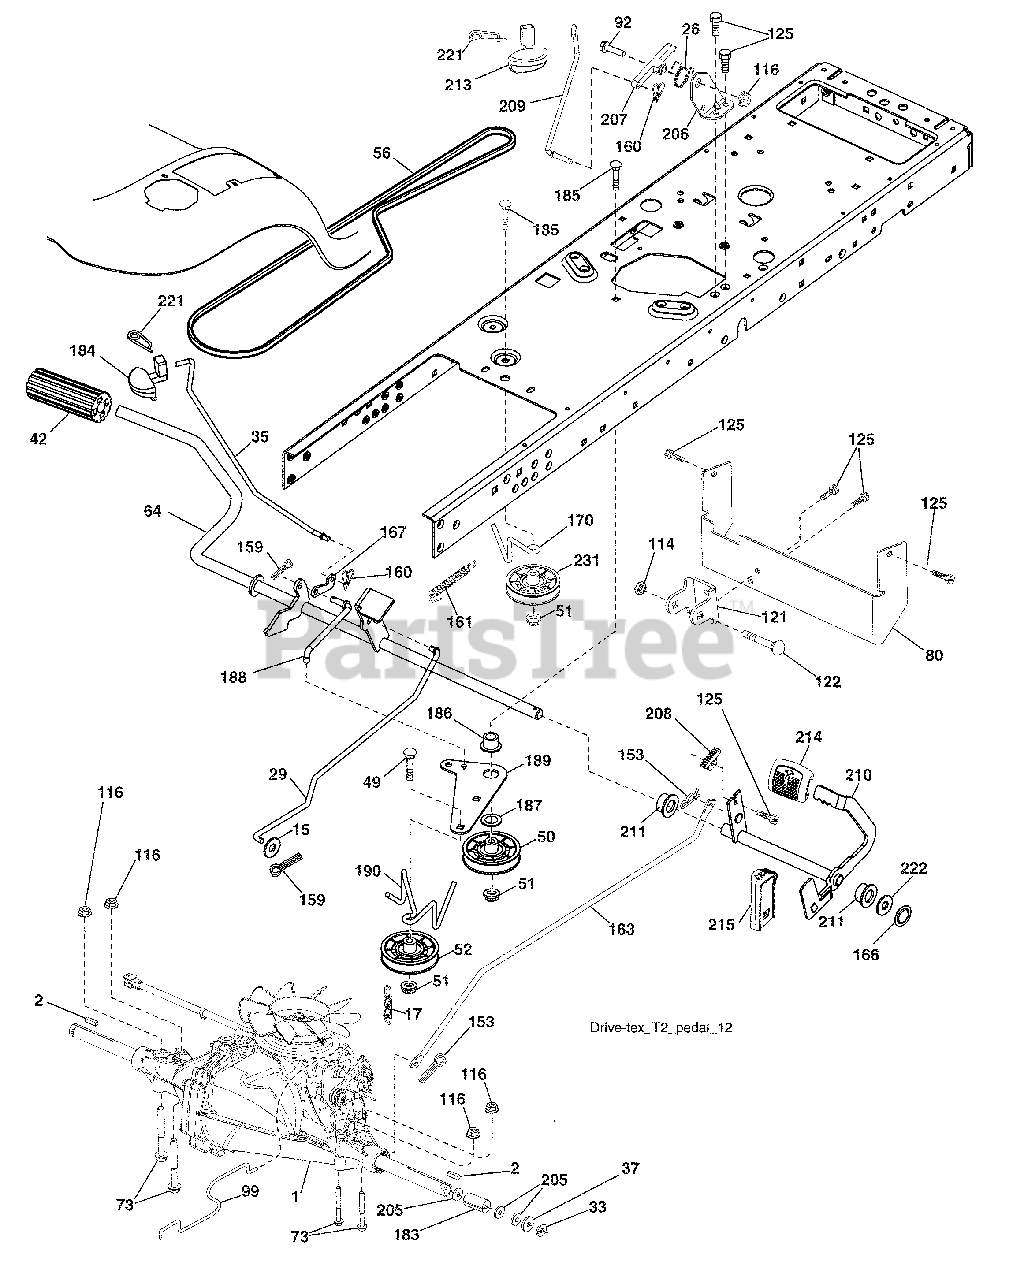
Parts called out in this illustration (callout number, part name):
2	Key Square
15	Washer 13/32 x 13/16 x 16 Ga.
17	Spring, Brake
26	Spring Return Cruise
29	Rod, Brake
35	Rod, Brake, Park
37	Washer 25/32 x 1-1/4 x 16 Ga.
42	Cover, Foot Pedal
50	Pulley Idler Flat
51	Lock Nut 3/8-16
52	Idler V-Groove 910" Offset
56	V-Belt, Drive
64	Shaft Asm. Pedal Brake Control
73	Bolt Hex 5/16-18 Gr. 5
80	Strap Torque
92	Bolt Fin Hex 5/16-18 unc x 1.25
99	Rod Spring Bypass
114	Nut Lock HX w/Ins 5/16-18
116	Nut Lock Hex Flange 5/16-18
121	Bracket Strap Torque
122	Bolt 5/16-18 x 2.50
125	Screw 5/16-18 x 3/4
153	Retainer Spring 1"
159	Pin Cotter 1/8 x 3/4
160	Retainer Clip
161	Spring, Return, Clutch
163	Rod Control
166	Nut Push
167	Latch Brake Parking
170	Keeper V-Idler
183	Spacer Axle
184	Handle Parking Brake
186	Spacer Retainer
187	Washer
188	Link Clutch Ground Drive
189	Bellcrank Ground Drive
190	Keeper Bellcrank Ground Drive
205	Washer 25/32 x 1-5/8 x 16 Ga.
206	Bracket Mount Latch Cruise
207	Latch Control Cruise
208	Gear Sector Control Cruise
209	Rod Control Cruise
210	Rocker Asm. Pedal Control
211	Bearing Nylon
213	Knob Control Cruise
214	Pedal Forward
215	Pedal Reverse
221	Retainer Spring Clip Handle
222	Washer 21/32 x 1-1/4 10 Ga.
231	Idler V-Groove 1.688" Offset
